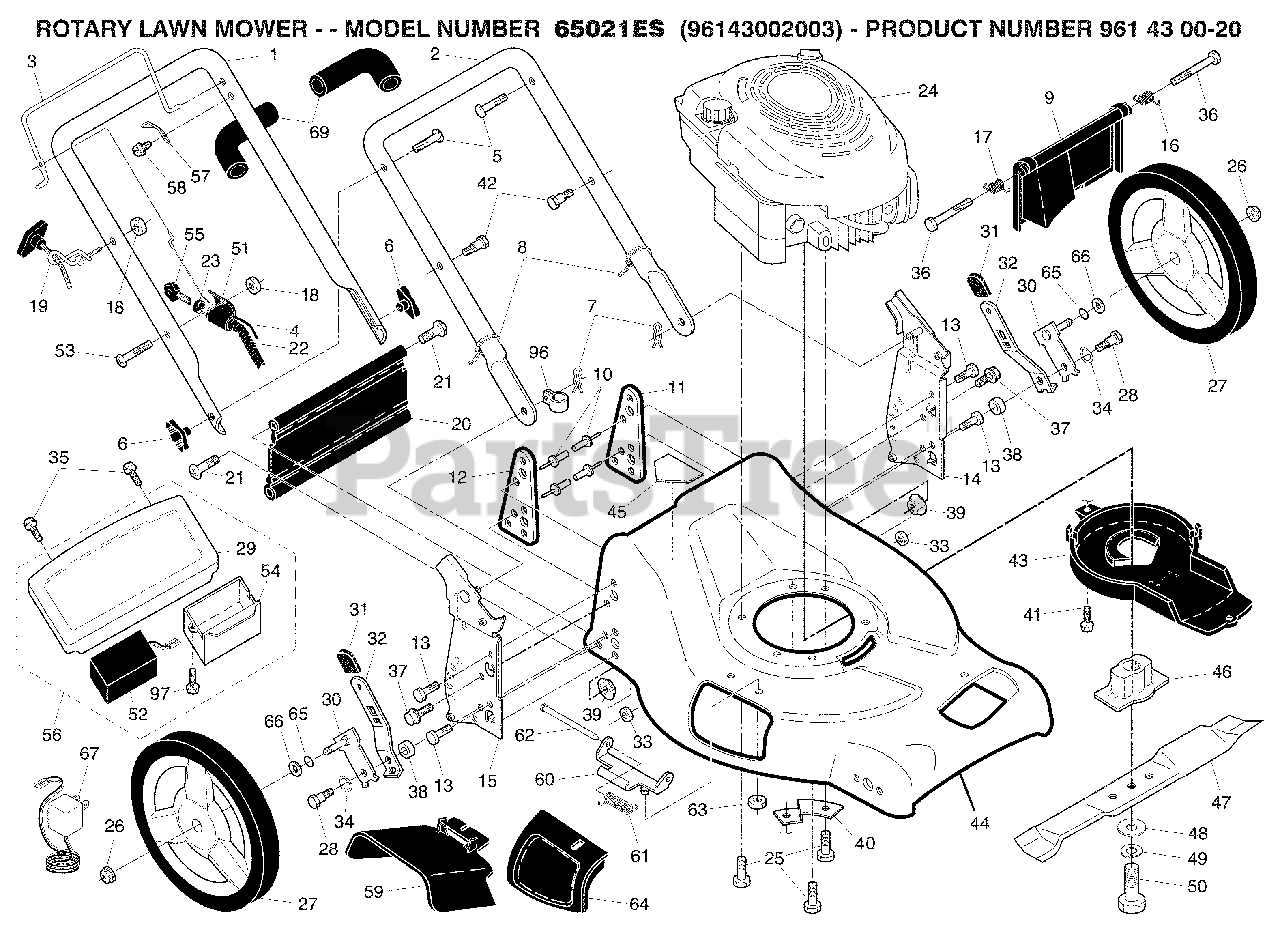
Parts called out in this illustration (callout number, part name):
1	Upper Handle
2	Lower Handle
3	Control Bar
4	Cable, Motor Zone Control
5	Handle Bolt
6	Handle Knob
7	Hairpin Cotter
8	Wire Tie
9	Rear Door Assembly
11	Support Bracket, LH
12	Support Bracket, RH
13	Screw 1/4-20 x 5/8
14	Handle Bracket Assembly, LH
15	Handle Bracket Assembly, RH
16	Spring, Rear Door, LH
17	Spring, Rear Door, RH
18	Keps Locknut 1/4-20
19	Rope Guide
20	Rear Skirt
22	Wiring Harness
25	Hex Head Thread Rolling Screw 3/8-16 x 1-1/8
26	Hex Flange Nut
27	Wheel & Tire Assembly, Rear
28	Shoulder Bolt 5/16-18 x .33
29	Trim Panel
30	Axle Arm Assembly
31	Selector Knob
32	Selector Spring
33	Nut, Hex 5/16-18
34	Washer, Curved, Cylindrical
37	Bolt
40	Mounting Bracket, Debris Shield
43	Debris Shield
44	Kit, Lawn Mower Housing
45	Danger Decal
46	Blade Adapter
47	Blade, 21"
48	Hardened Washer
49	Helical Washer 3/8-24 x 1-3/8 Grade 8
50	Hex Head Machine Screw 3/8-24 x 1-3/8 Grade 8
51	Key Start Switch
52	Battery
54	Battery Box
56	Trim Panel / Battery / Battery Box Assembly
57	Upstop Bracket
59	Discharge Deflector
60	Hinge Bracket
63	Nut, Hex
64	Mulcher Door
66	Washer, Flat 1/2
67	Charger, Battery
69	Grip, Foam
96	Clip, Cable
